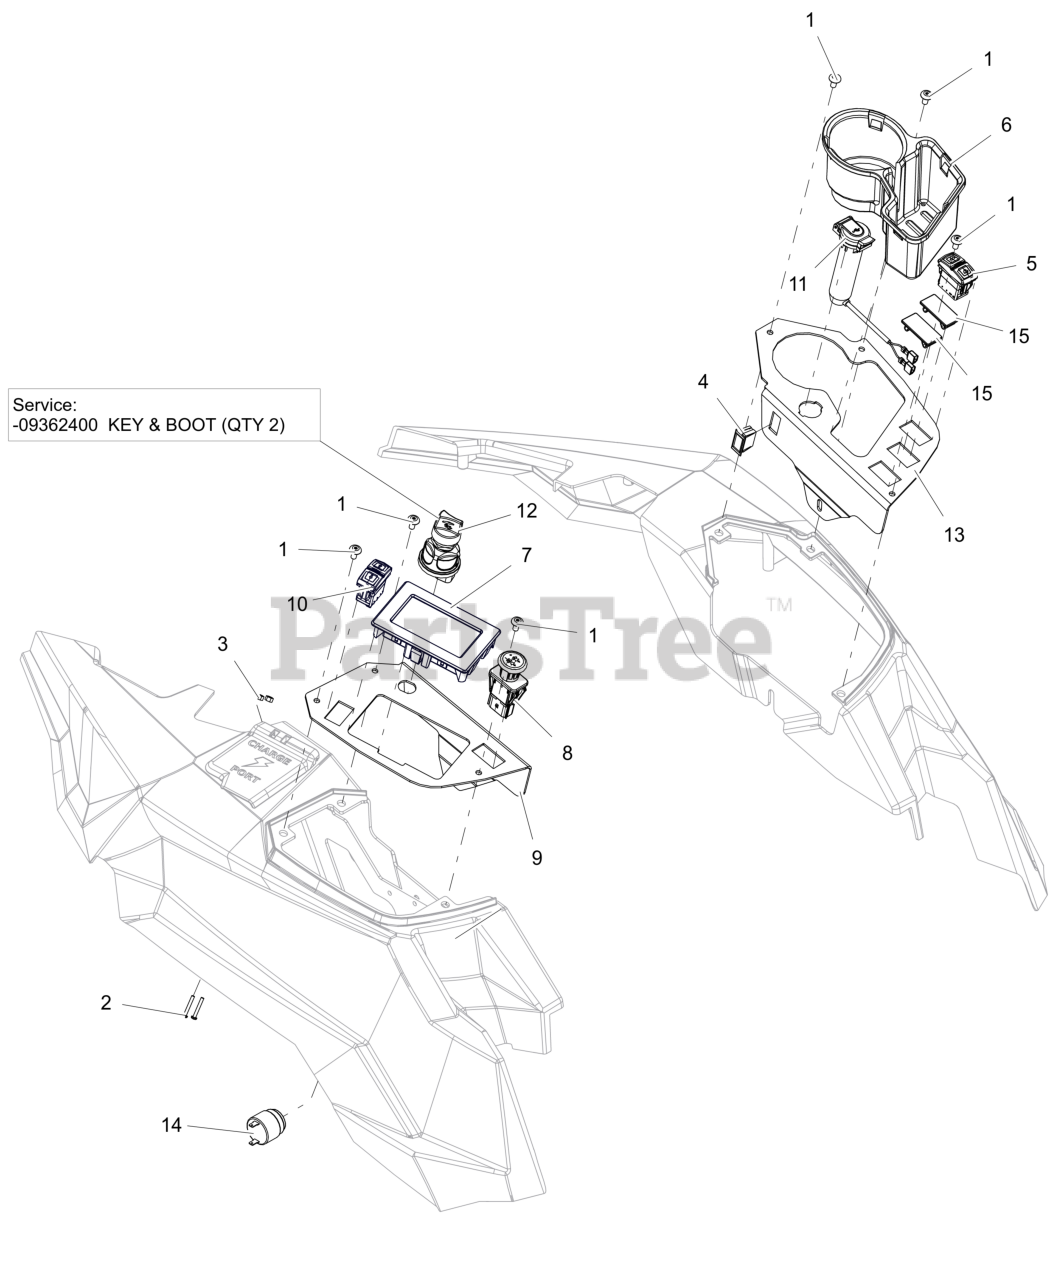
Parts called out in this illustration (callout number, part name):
1	SCR, MCH .25-20 X .500 TXTR ZB500
2	SCR, PH PAN HD #6-32X1.000 ZCC
3	@NUT-LK-NYL 6-32 W/INSRT YWZC
4	SWITCH,BLANK
5	SWITCH, TOGGLE - SPEED
6	HOLDER, CUP
7	DISPLAY, GRAVELY
8	SWITCH, PTO (SEALED)
9	PANEL, CONTROL -RH (RED)
10	SWITCH, ROCKER - DISPLAY
11	PLUG, CHARGER USB
12	SWITCH, KEY (SEALED)
12	KEY & BOOT (QTY 2)
13	PANEL, CONTROL -LH (RED)
14	ALARM, AUDIBLE
15	PLUG, SWITCH
